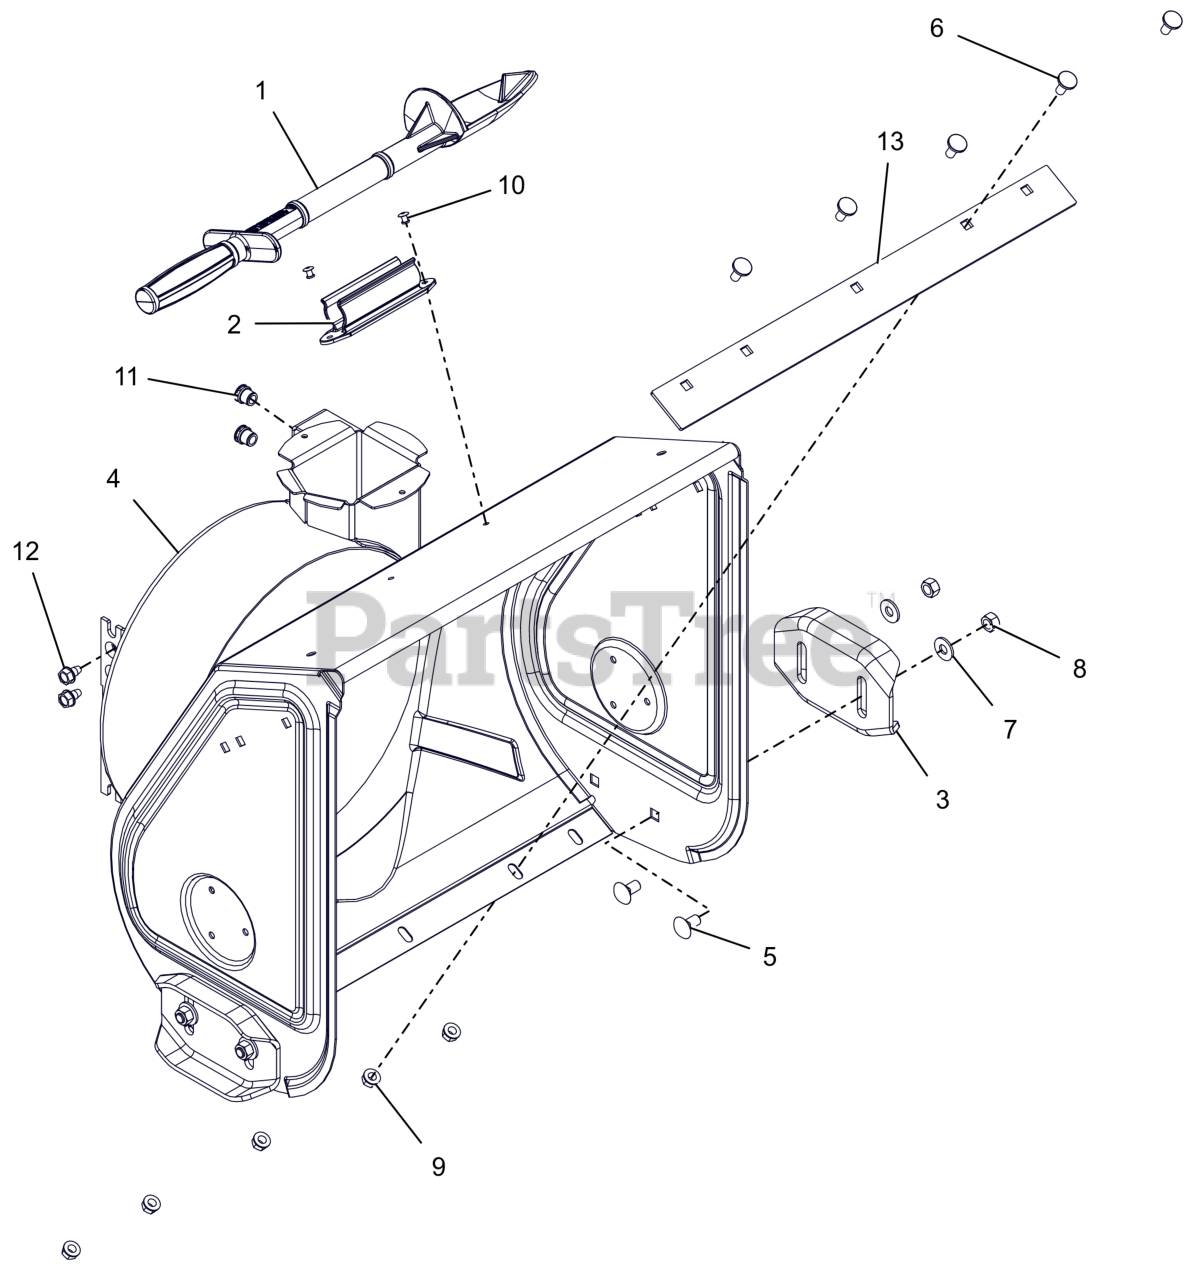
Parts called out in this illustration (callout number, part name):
1	DEVICE, SNOW CLEAN OUT
2	MOUNT, SNOW CLEAN OUT
3	SKID SHOE, REVERSIBLE - ORANGE
4	BLOWER HOUSING, 20" HB SERVICE
5	BLT, RHSSN .38-16X.75 G5 ZCC
6	BOLT, MODIFIED HEAD CARRIAGE
7	WSHR,FLT .375X.875X.083 ZCC
8	NUT-LK-CTR .38-16 ZC120
9	NUT-LK-TOP-FLG .312-18 GF ZCC
10	RVT, POP .1875 ZCC
11	NUT,THD,INSERT .38-16 ZC120
12	SCR,TAP .312-18X.50 HWH TR ZCC
13	SCRAPER BLADE, 20"
